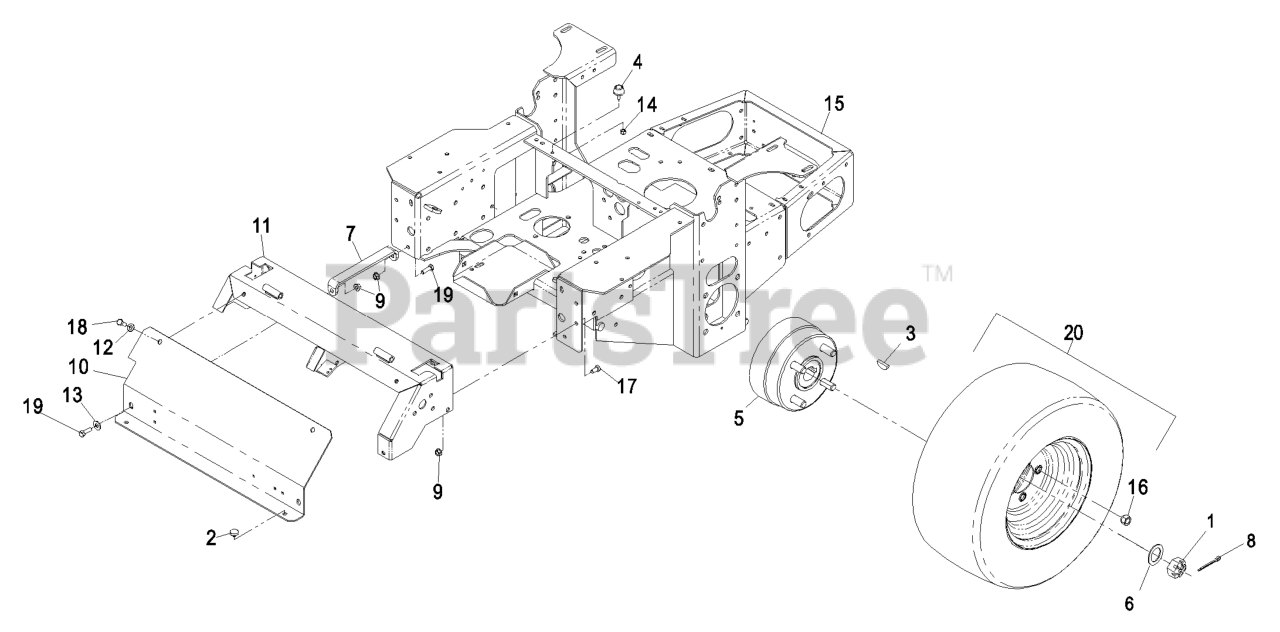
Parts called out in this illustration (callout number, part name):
3	KEY-WOODRUFF
5	WHEEL HUB ASM
6	WASHER-SPACER
8	PIN-COTTER
11	ASM,CONSOLE WELDMENT W/DE
12	WASHER-PLAIN
13	WASHER-FLAT
15	Wld, Mainframe
16	NUT-LUG
17	SCREW-HH
18	SCREW-HH
19	SCREW-HH
20	WHEEL AND TIRE ASM
